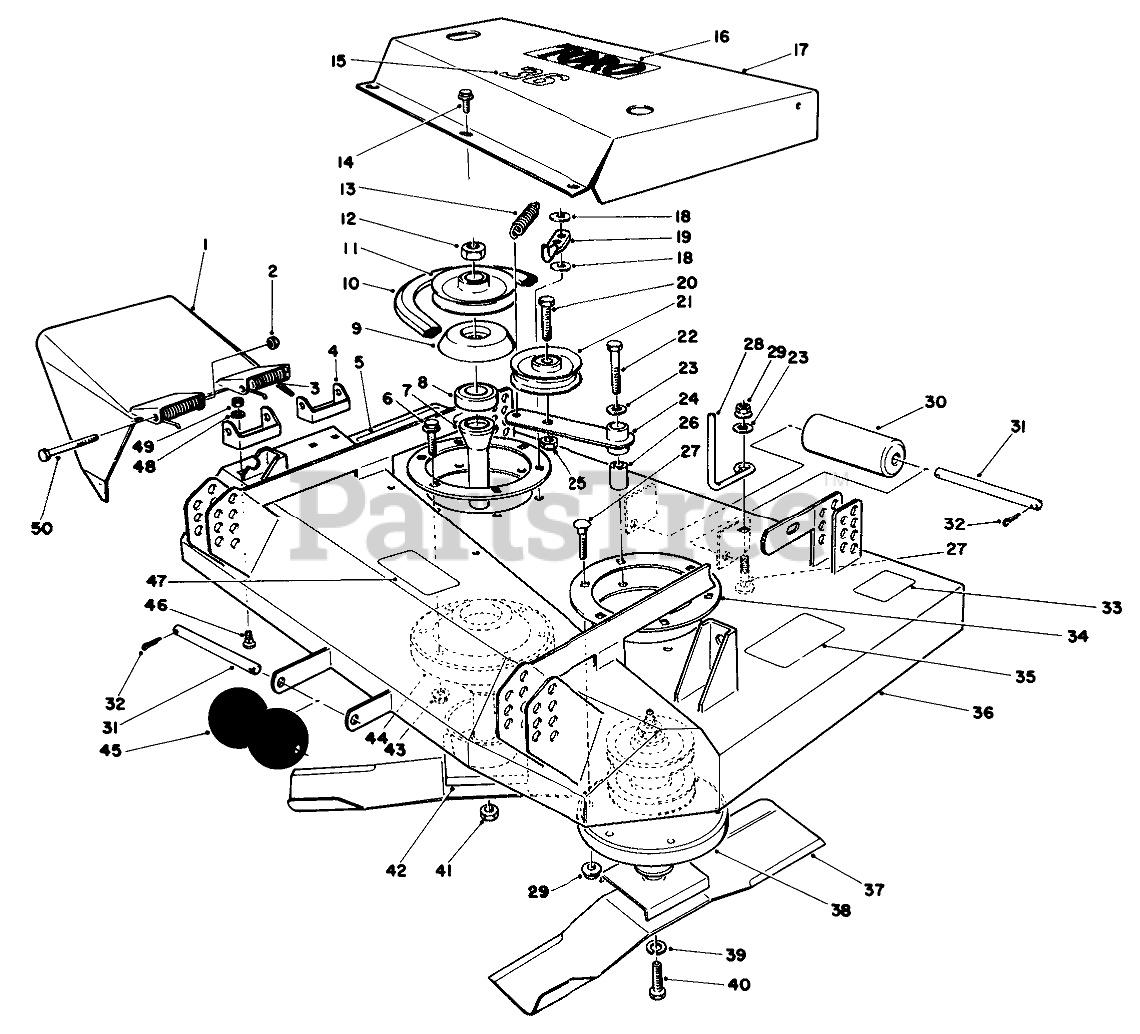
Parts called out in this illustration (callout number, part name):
1	Deflector-Grass
2	NUT-HEX
3	SPRING
4	Bracket-Pivot
5	DECAL-CAUTION, DEFLECTOR
6	SCREW-HHF
7	SPACER-GREASE SHIELD
8	BEARING
9	COVER-DUST
10	V-BELT-DRIVE, DECK
11	PULLEY and HUB ASM
12	Locknut
13	SPRING-EXTENSION
14	SCREW-HHFTF
15	Decal-36 Inch
16	Decal-Toro
17	COVER-DECK
18	WASHER-FLAT
19	ROD-SPRING
20	SCREW-HH
21	PULLEY-IDLER
22	SCREW-HH
23	WASHER-FLAT
24	ARM-IDLER, DECK
25	NUT-HEX
26	SLEEVE
27	SCREW-CARR
28	ROD-BELT
29	NUT-HF
30	ROLLER-DECK
31	SHAFT-ROLLER
32	PIN-COTTER
33	DECAL
34	SUPPORT-DECK, RING
35	DECAL-CAUTION, BLADE
36	Deck
37	Blade
38	SPINDLE ASM
39	WASHER-LOCK/SP
40	SCREW-BLADE
41	Locknut
42	SHAFT and SADDLE ASM
43	NUT-HF
44	Spindle ASM
45	ROLLER
46	SCREW-CARR
47	Decal-Caution
48	WASHER-LOCK
49	NUT-HEX
50	SCREW-HH
